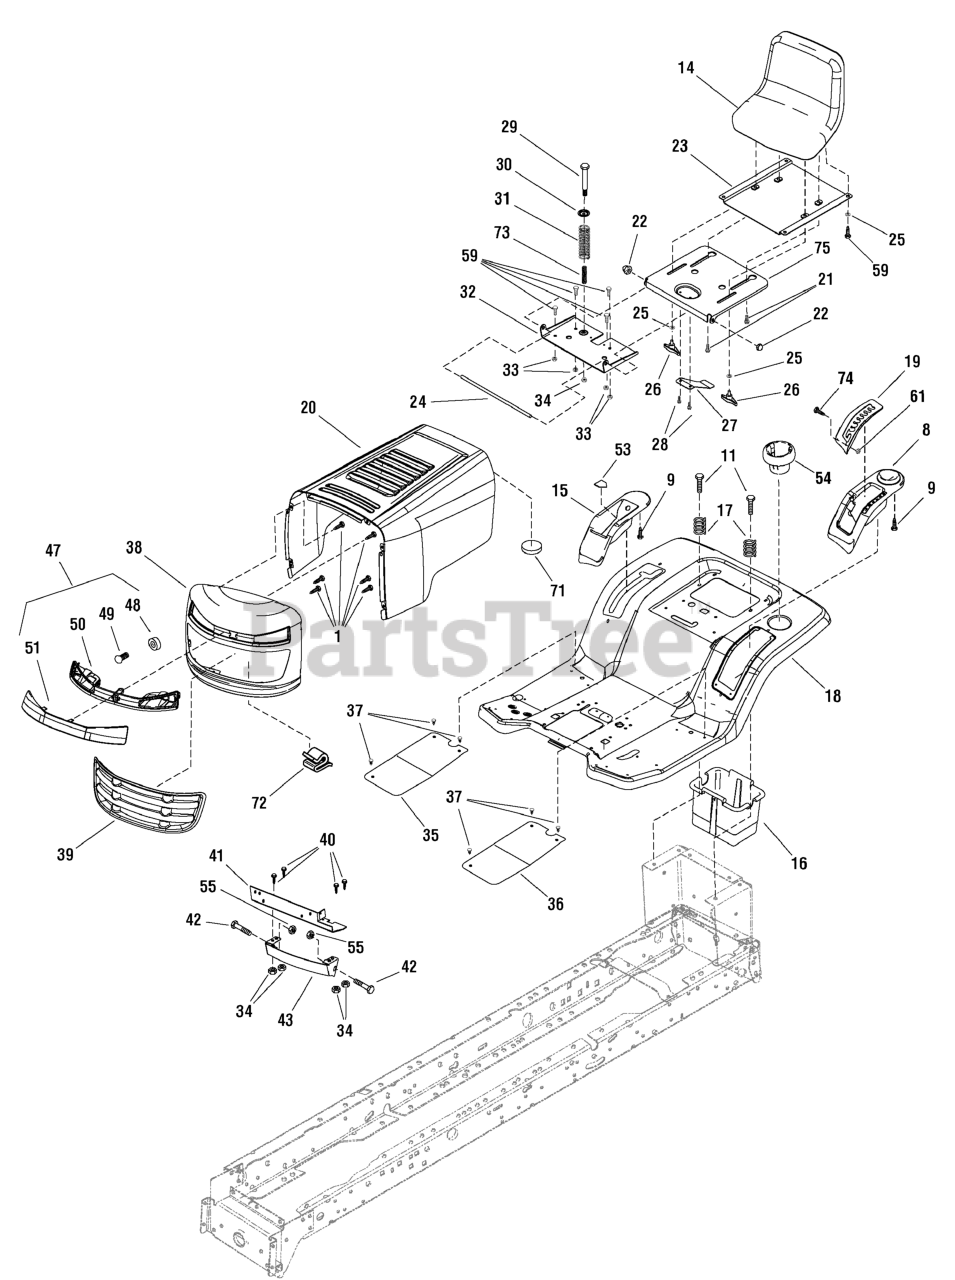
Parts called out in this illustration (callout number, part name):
1	SCREW, Thread Forming
8	POD, With Cup Holder
9	SCREW, Thread Cutting 1/4-20
11	SCREW, 5/16-18 x 3/4
14	SEAT, Low Back
14	SEAT, High Back
15	POD, With Compartment
16	CONTAINER, Battery
17	SPRING, Compression
18	DECK, Seat
19	PLATE, Index
20	HOOD
20	HOOD, with Studs
21	BOLT, Shoulder 5/16-18 x 3/8
22	CAP, Push On
23	SEAT PLATE
24	ROD, Pivot
25	WASHER, Flat, 3/8
26	BOLT, Wing
27	SPRING, Leaf
28	SCREW, 1/4-14 x 3/8
29	BOLT, Shoulder, 1/4-20 x 5/16
30	WASHER, Cup
31	SPRING, Compression
32	BRACKET, Seat Pivot
33	NUT, Nylock 5/16-18
34	NUT, Hex Flange Lock, 1/4-20
35	MAT, Running Board, Right
35	MAT, Molded, Right
36	MAT, Running Board, Left
36	MAT, Molded, Left
37	FASTENER, Panel
38	GRILLE
39	LOUVER, Insert
40	SCREW, 1/4-20 X 5/8
41	BRACKET, Support
42	BOLT, Shoulder
43	BRACKET, Lower Pivot
47	ASSEMBLY, Headlight
48	SOCKET, Light
49	BULB, 12.8V
50	HOUSING, Light
51	LENS, Light
53	INDICATOR, Cutting Height
54	HOLDER, Beverage
55	NUT, Centerlock, 3/8-16
59	BOLT, HEX, 5/16-18 x 5/8
61	NUT, #10-24
73	SPRING, Brake Compression
74	SCREW, Shoulder #10-24
75	SUPPORT, Seat
